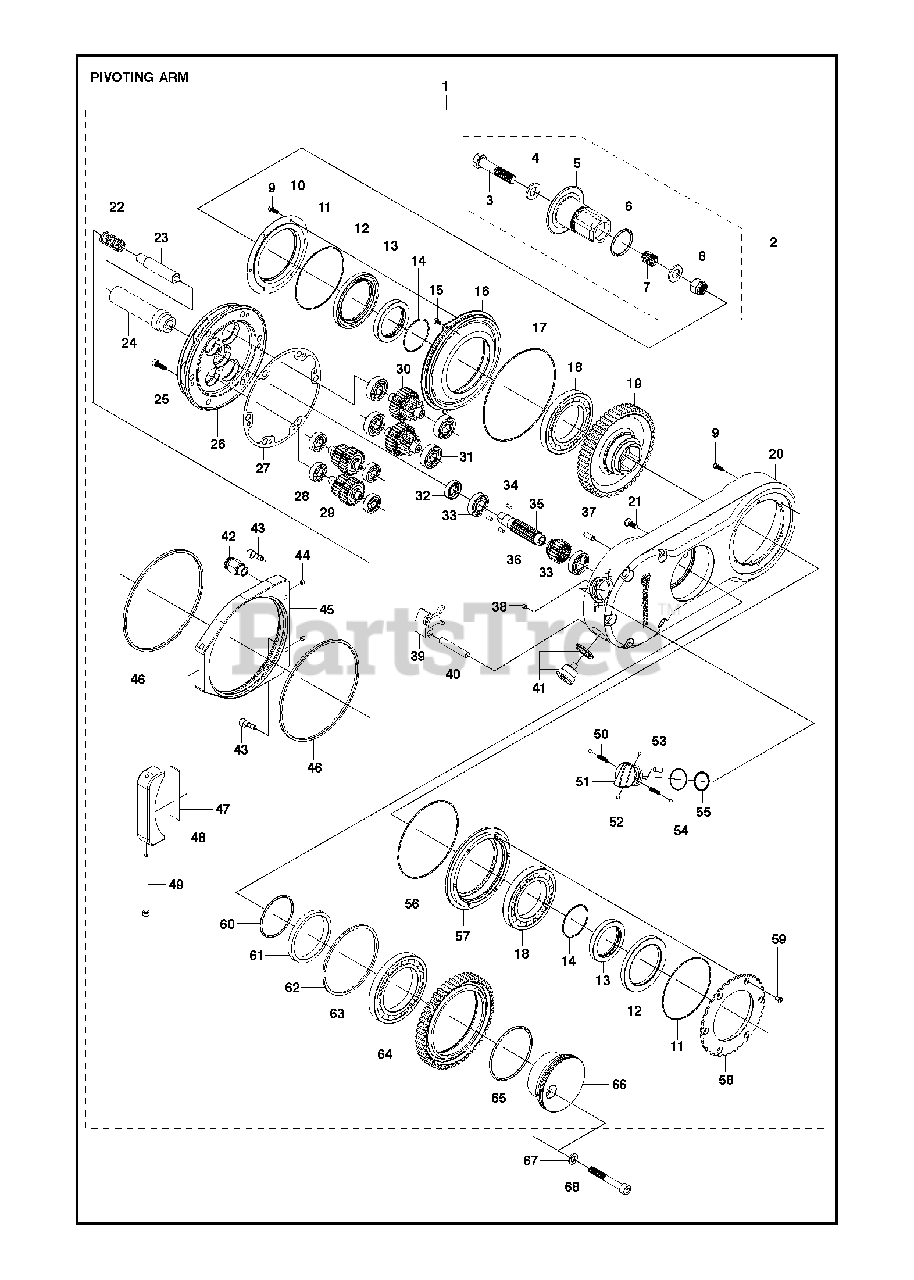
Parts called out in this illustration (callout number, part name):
1	PIVOTING ARMIncl. 2 - 66
2	SHAFT ASSYIncl. 3 - 8
45	COOLING AIR CONDUCTOR
67	WASHER
